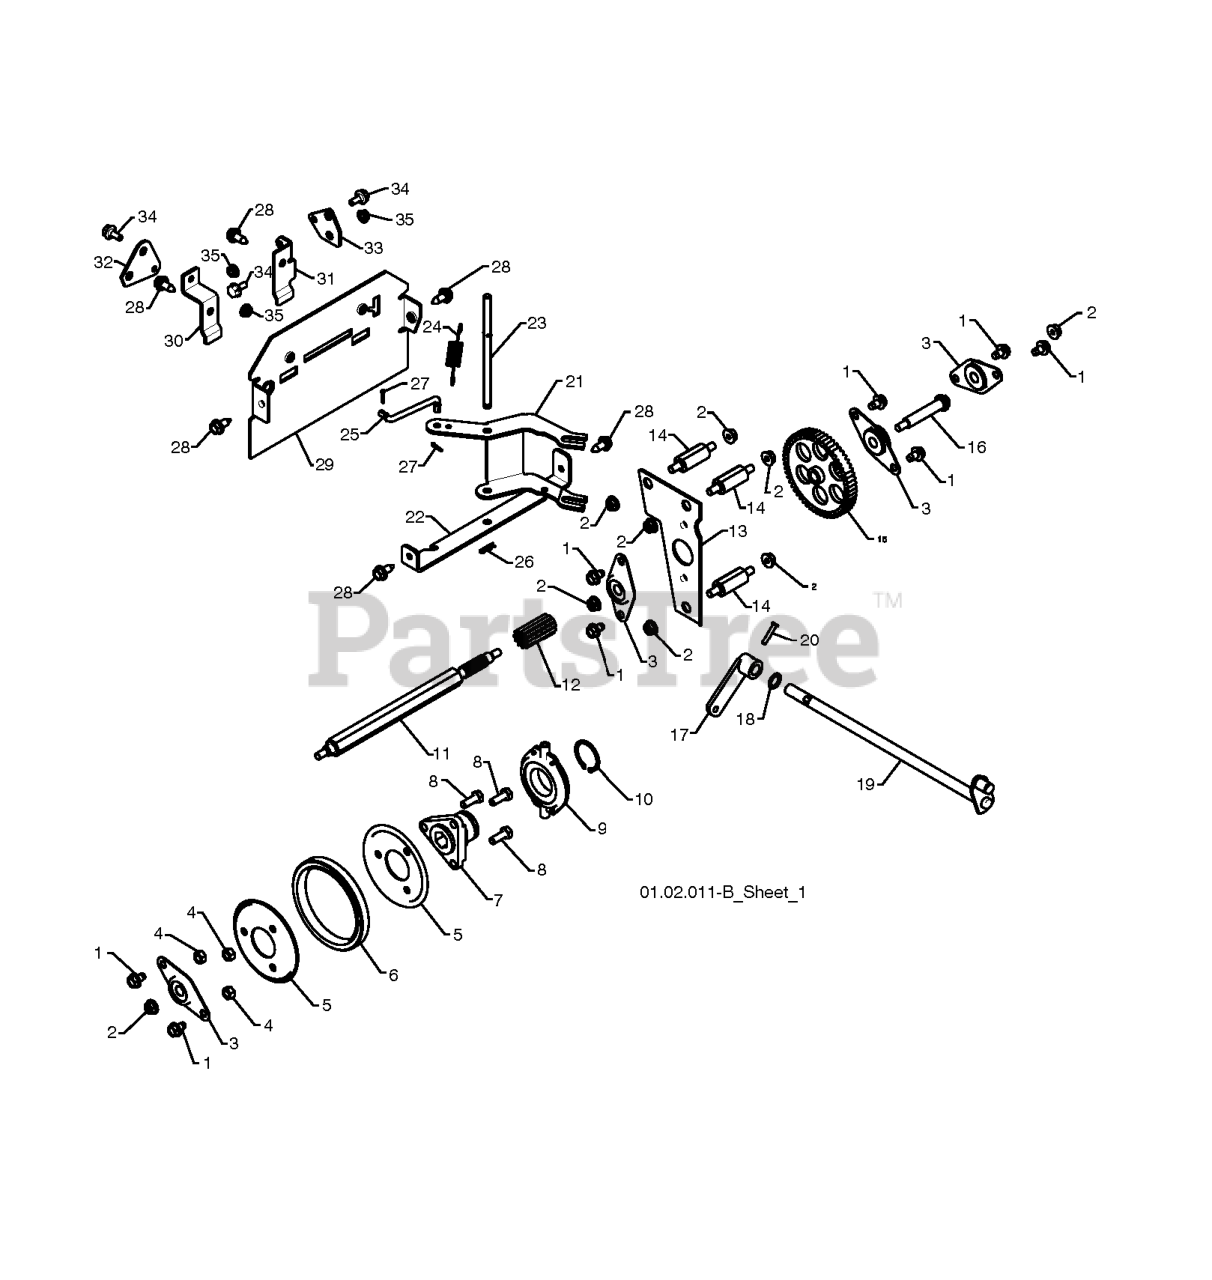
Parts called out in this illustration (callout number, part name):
1	Screw 5/16-18 x 1/2 Hex, Self Tapping 5/16-18 x 1/2
2	NUT.LOCK.5/16-18
3	BEARING, FLANGE
4	NUT.CENTERLOCK.5/16-
5	PLATE.RUBBER.WHEEL
6	RING, RUBBER WHEEL
7	HUB, RUBBER WHEEL
8	BOLT
9	TRUNNION BEARING ASSY
10	RETAINING RING (2 2)(3 2)
11	SHAFT.HEX.LONG
12	GEAR, PINION
13	AUXILLARY PLATE
14	SPACER, PLATE
15	GEAR, INTERMEDIATE
16	SHAFT, AUXILIARY
17	ARM, AUGER CONTROL
18	THRUST WASHER
19	CONTROL.SHAFT.ASM
20	CLEVIS PIN
21	LEVER, SPEED CONTROL
22	BRACKET, PIVOT, SHIFT
23	PIN, PIVOT
24	SPRING, BIAS
25	LINK, SPEED CONTROL
26	RETAINER CLIP PM
27	RETAINER CLIP
28	BOLT.HEX.HD.WASHER.5/16-18X.75
29	PLATE.REAR.SNOW.PNT.ORANGE
30	BRACKET.SHIFTER.PLATE.BZP
31	BRACKET.CLUTCH.PLATE.BZP
32	PLATE.SHIFTER.BZP
33	PLATE.CLUTCH.BZP
34	BOLT.SHOULDER.3/X.25
35	NUT.HEX.FLANGE.1/4
